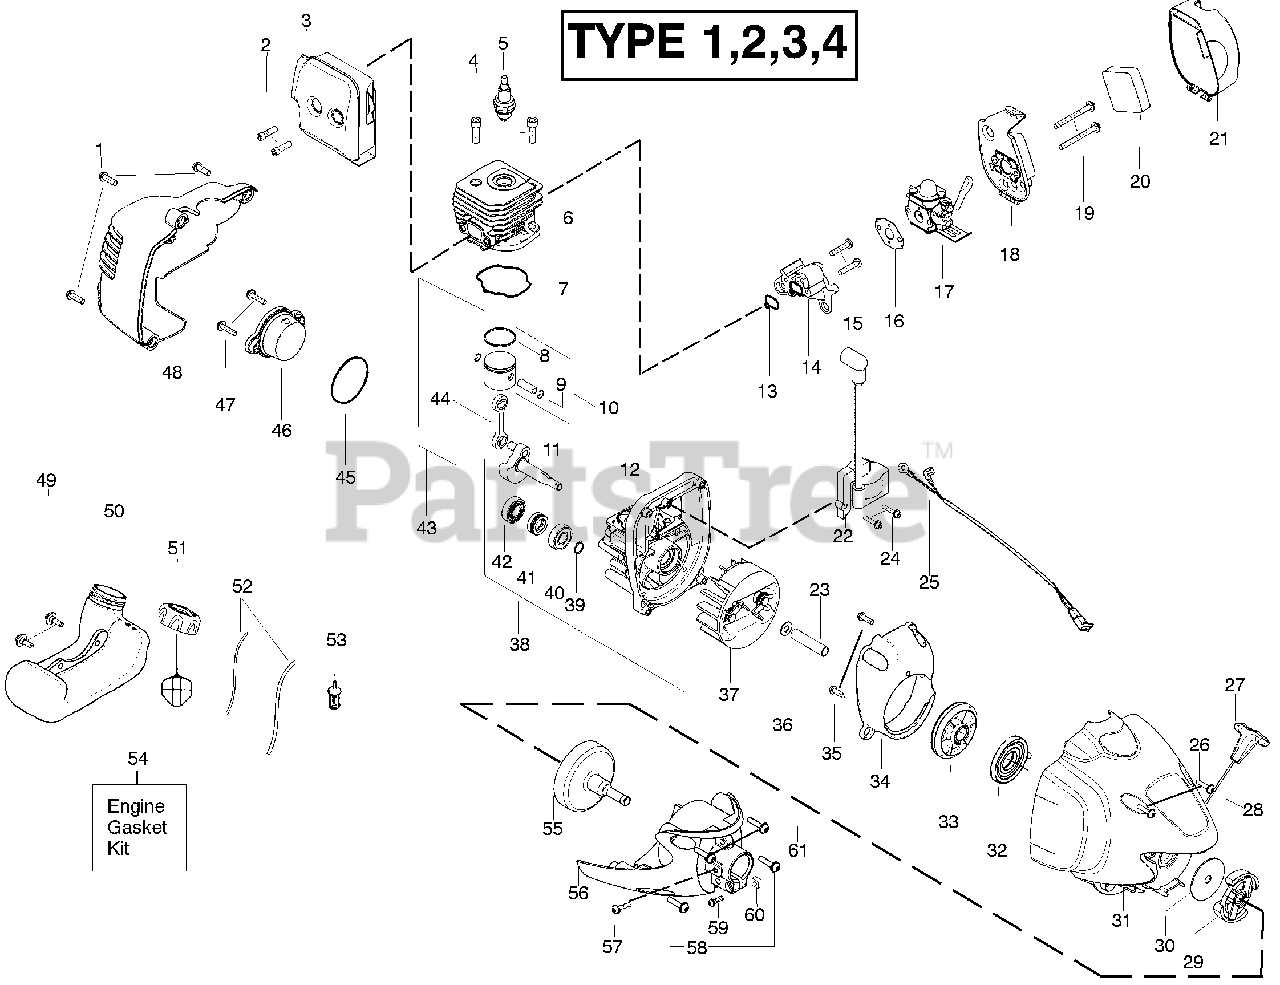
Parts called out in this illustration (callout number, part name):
2	BOLT MUFFLER
3	ASSY MUFFLER SHIELD
5	PLUG-SPARK (RCJ-6Y)
6	CYLINDER MACHINED 25CC LO
8	RING PISTON
9	WRIST PIN RET.
10	PISTON KIT
11	ASSY CRANKSHAFT
12	ASSY CRANKCASE
14	ADAPTOR CARBURETOR
17	KIT CARB ASSY
18	BASE AIR BOX PP GOLD
20	AIR FILTER
21	COVER AIR BOX FE
22	%MODULE IGNITION
23	SPACER FLYWHEEL
25	LEAD WIRE ASSEMBLY
27	HANDLE STARTER BLK
28	KIT ROPE
29	ASSEMBLY CLUTCH
30	WASHER-CLUTCH
32	SPRING STARTER SA
33	KIT STARTER PULLEY
34	BAFFLE FAN
36	WASHER CLUTCH
37	ASSY FLYWHEEL
38	ASSY CRANKCASE & CRANKSHAFT
39	RETAINING RING
40	OUTER BEARING
42	BEARING
43	PISTON KIT
44	CONNECTING ROD ASSY
46	ASSY REAR PLUG
48	SHROUD REAR BLACK
49	SCREW FUEL TANK RETAINER
51	FUEL CAP ASSY
52	KIT LINE FUEL LOW PERM .188
53	Pre-Flushed Fuel Pick-up Assembly
54	KIT GASKET 25CC
55	ASSY CLUTCH DRUM W/ADPT
56	ASSY CLUTCH COVER
58	SCREW-10-24 X 1" (TAP.)
59	SCREW 12-24 X 5/8
60	NUT SQUARE 12-24
